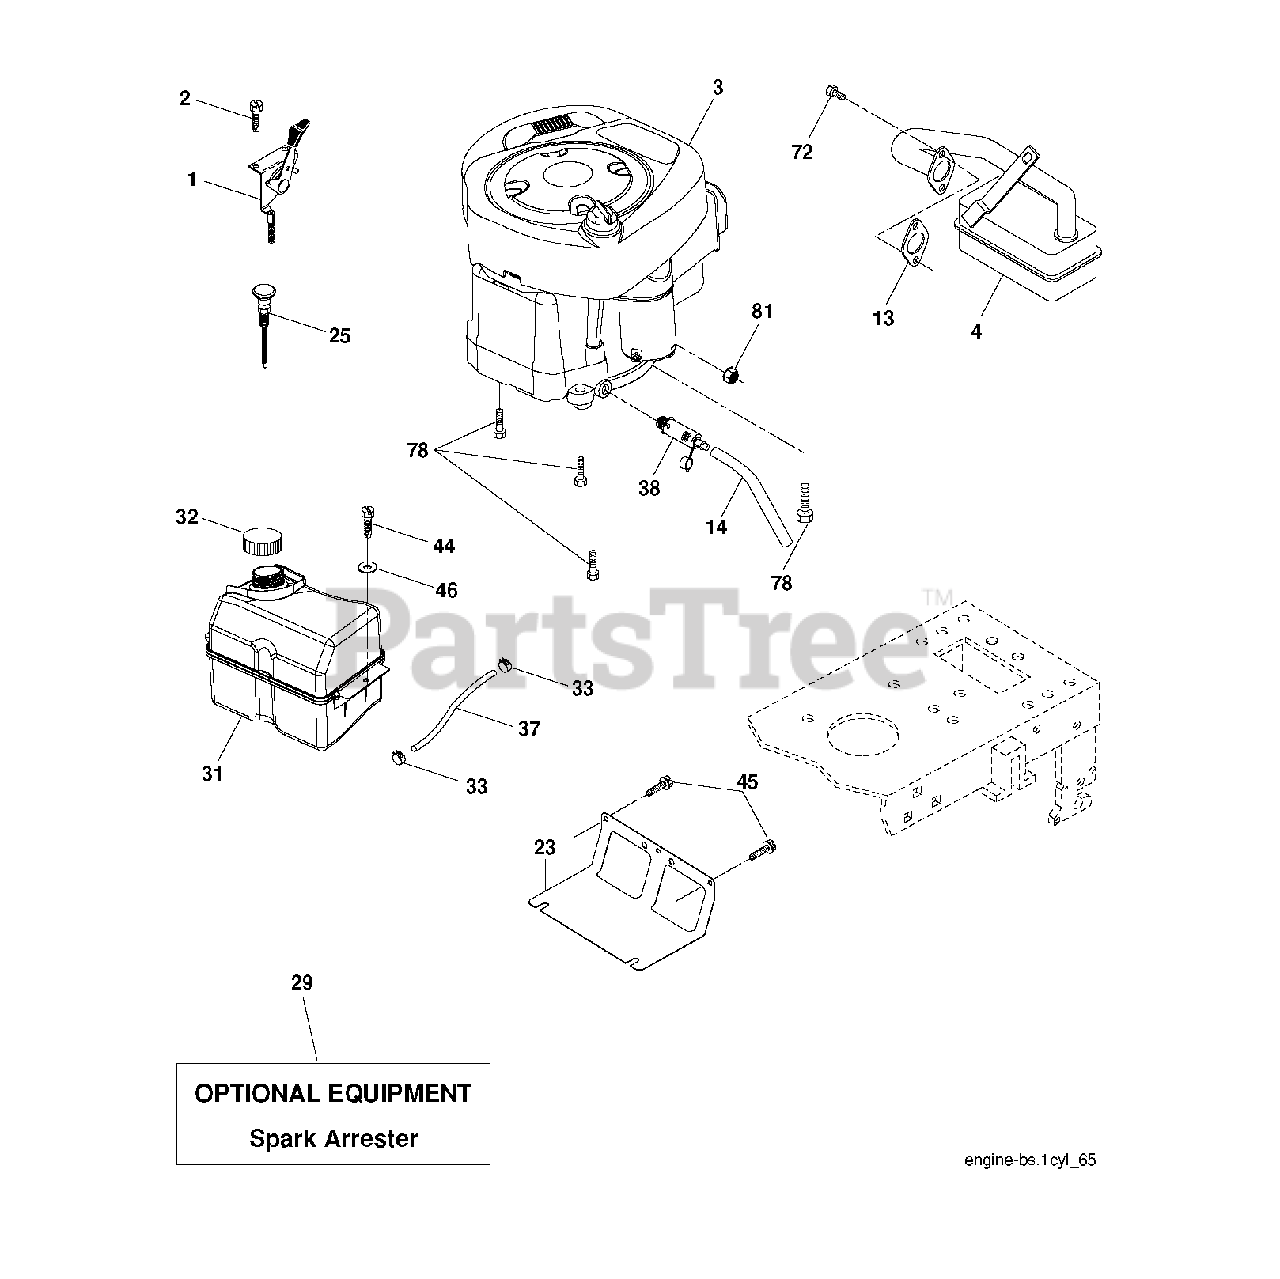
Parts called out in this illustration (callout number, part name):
1	CONTROL TH/CH FLAG
2	SCREW
13	REPL BY 532 27 22-93
14	TUBE, DRAIN OIL ASM.
23	SHEILD.BROWNING.DBR.GUARD
29	ARRESTER SPARK (OPTIONAL)
32	FUEL CAP
33	HOSE CLAMP
37	LINE.FUEL.20
38	PLUG DRAIN OIL EASY
44	SCREW HEXWSHR 1/4-20X3/4
45	SCREW, 3/8-16X3/4
72	SCREW.SOCKET HD.5/16-1
78	SCREW.3/8-16
81	NUT
